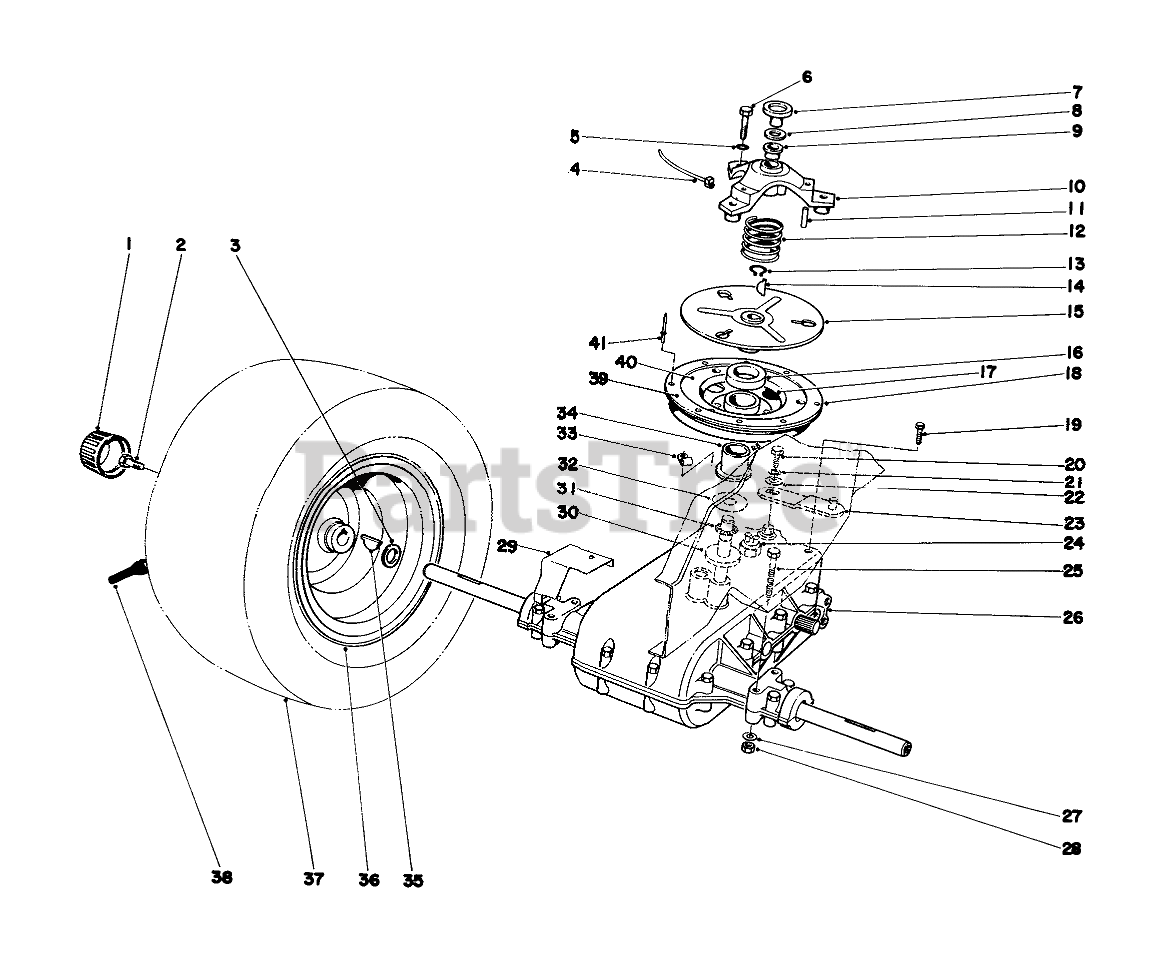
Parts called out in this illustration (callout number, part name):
1	Cap-Hub
2	CAPSCREW 3/8 16 3/4
3	SPACER-WHEEL
4	TIE-MOUNT, PUSH
5	WASHER-LOCK
6	SCREW-HH
7	CLUTCH CAP
8	THRUST RACE
9	BUSHING-FLANGE
10	Cover Clutch (Incl.Ref. #15& 17)
11	NEEDLE BRG
12	COMPRESSION SPRING
13	RING-SNAP, EXTERNAL
14	KEY-WOODRUFF
15	Clutch Plate
16	WASHER FELT
18	Sheave Assembly (Incl.Ref. #40 & 4648)
19	SCREW-HWHTF
20	SCREW-HH
21	WASHER-LOCK
22	WASHER-FLAT
23	SHIFT LEVER WA B
24	NEUTRAL SWITCH
25	SCREW-HH
26	Transaxle
27	WASHER-PLAIN
28	NUT-LOCK, CONE
29	GRASS SHIELD B
30	THRUST WASHER
31	NEEDLE BRG
32	THRUST WASHER
33	CLIP-FUEL LINE
34	Bushing
36	Rim
38	Tube
39	CLUTCH PAD
40	Rivet
41	Retainer Ring
